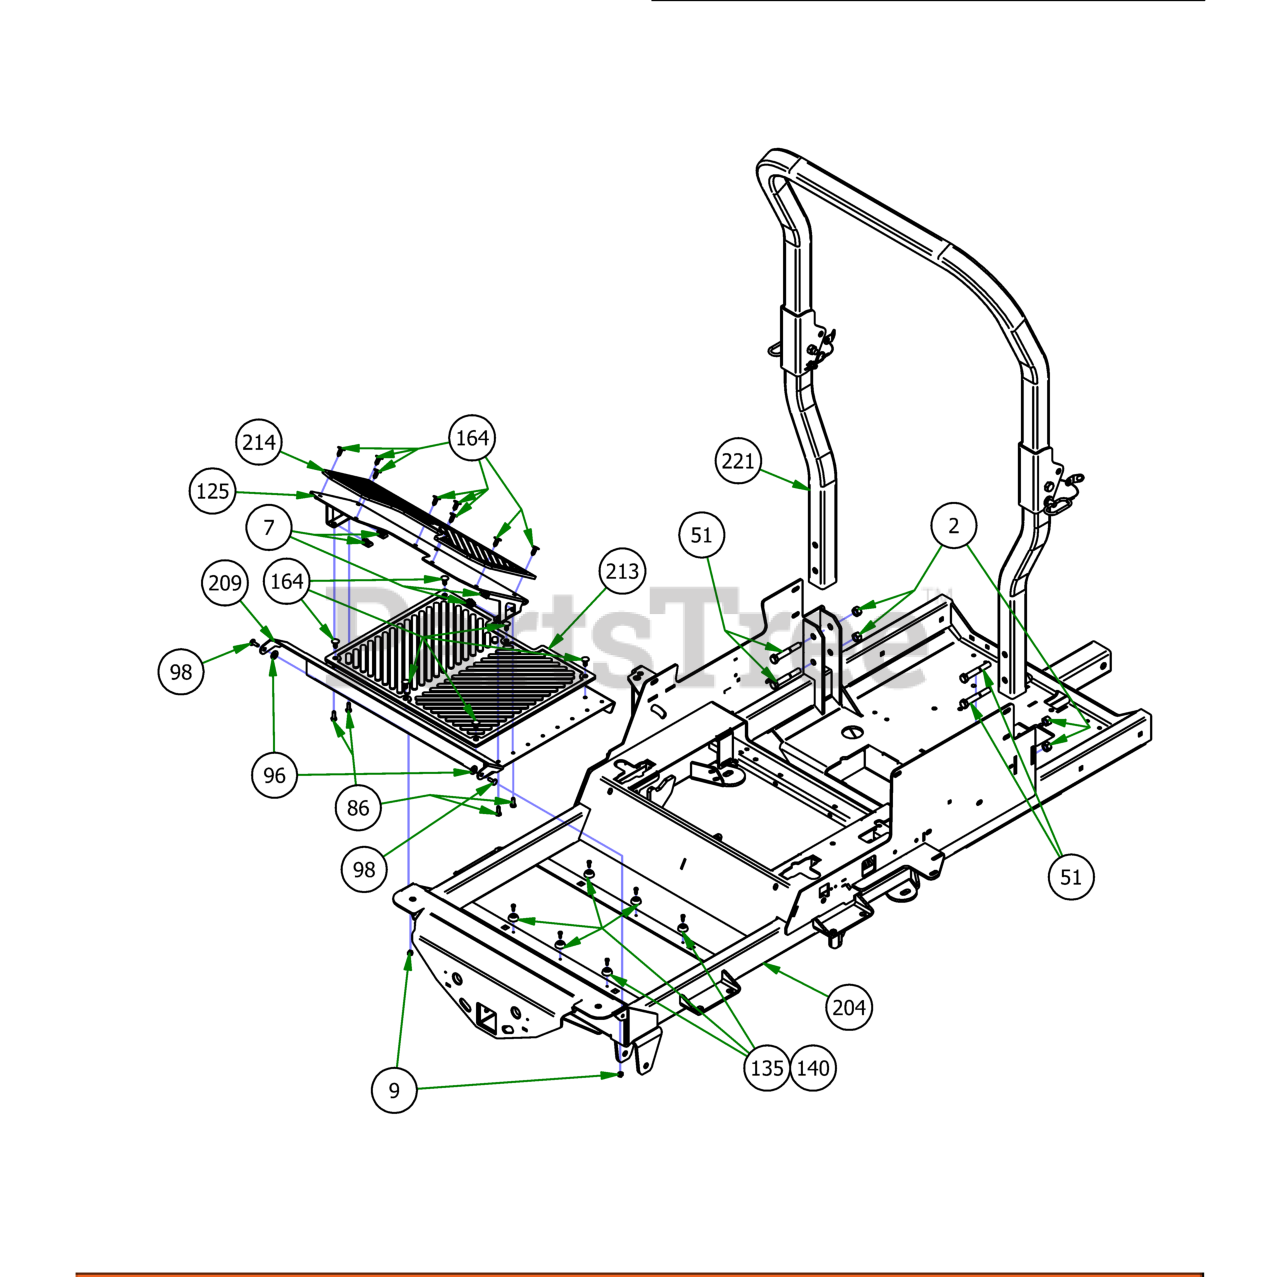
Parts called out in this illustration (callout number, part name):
2	1/2" Center Lock Nut
7	1/4-20 Cage Nut
9	1/4-20 Hex flang lock nut
51	1/2-13 X 3.25 Hex Bolt - Grade 5
86	1/4" x 3/4" Hex Bolt
96	.360 ID Plastic Washer
98	1/4" x 3/4" Carriage Bolt
125	2019 Outlaw Adjustable Foot Plate
135	Button Bumper
140	#10 x 1/2" Self Tapping Screw
164	Ratchet Fastener
204	2019 Renegade Gas Frame - Powdercoated
209	2019 Outlaw Floorboard
213	OUTLAW2019_FLOORMAT
214	FLOORMAT_OUTLAW_2019
221	2019 2X2 Folding ROPS
